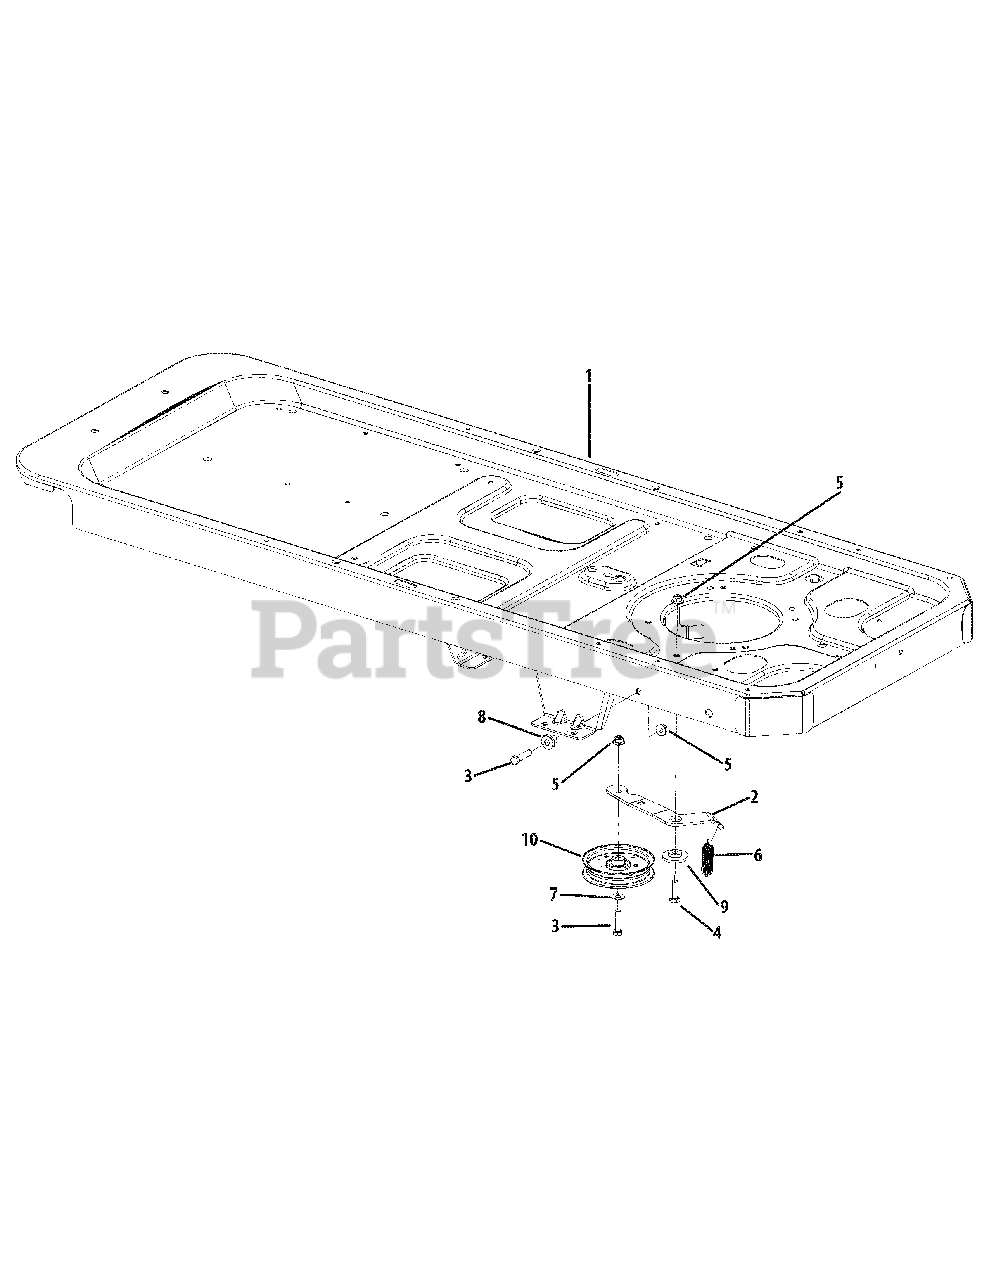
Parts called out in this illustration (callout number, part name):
1	Frame Assembly
2	Drive Idler Arm
3	Hex Screw, 3/8-16 x 1.5
4	Hex Screw, 3/8-16 x 1.25
5	Flange Nut, 3/8-16
6	Extension Spring, .75 x 5.06
7	Flat Washer, .408 x .875 x .059
8	Shoulder Spacer, .39 x 1.0 x .7
9	Shoulder Spacer, .884 x .19
10	Idler Pulley, 4.25 Dia.
